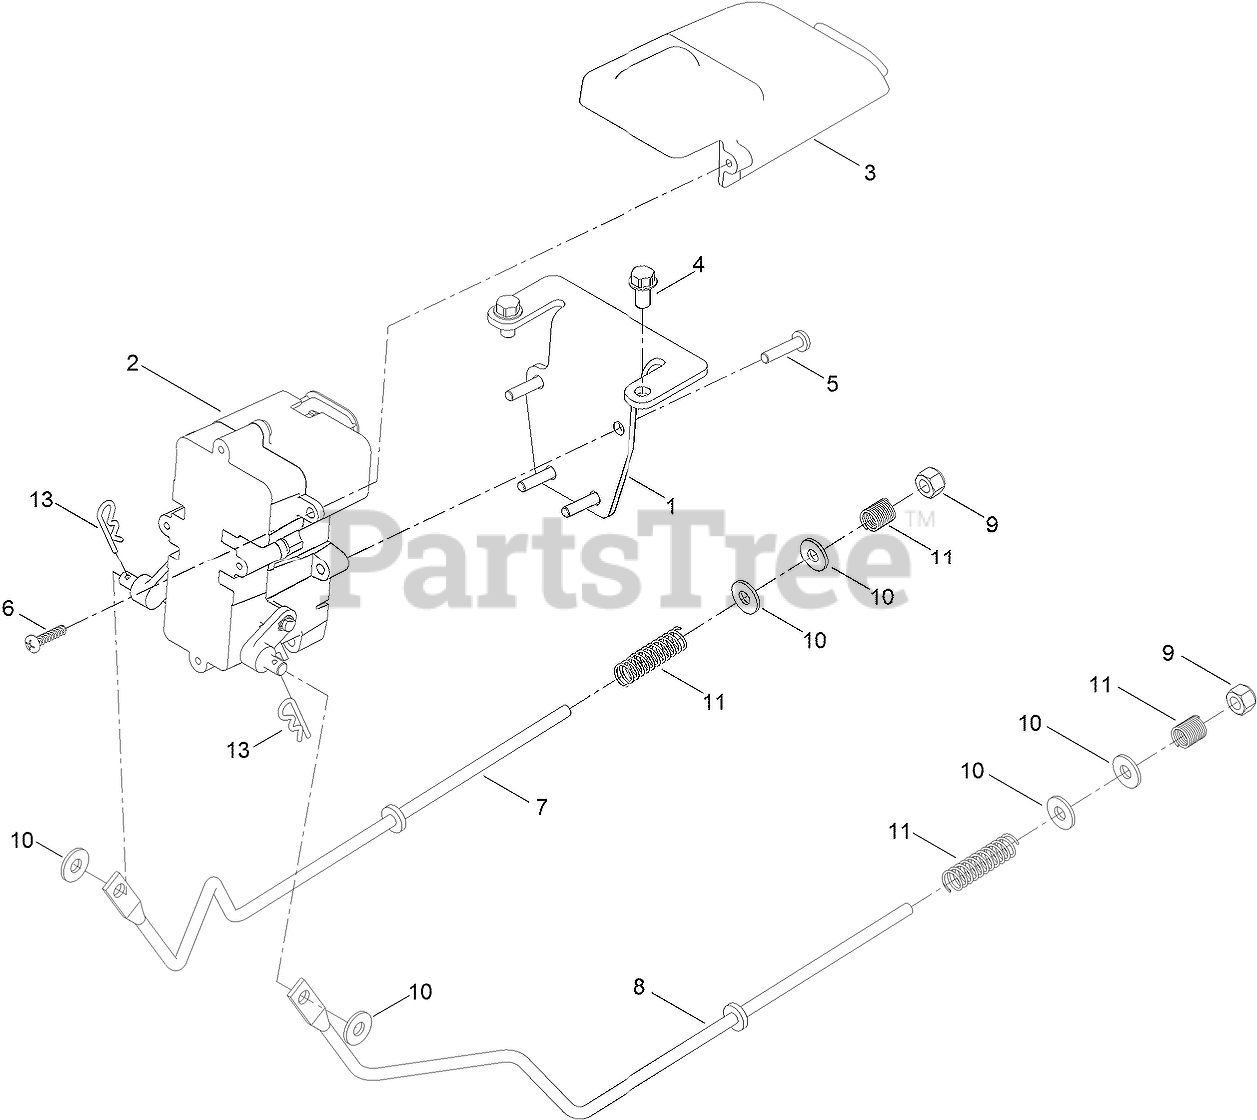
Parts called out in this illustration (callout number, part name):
1	BRACKET-MOUNT, BRAKE
2	BRAKE BOX ASM
3	COVER-CONNECTOR
4	SCREW-HWH
5	SCREW-PPH
6	SCREW-PPH
7	ROD-BRAKE, RH
8	ROD-BRAKE, LH
9	NUT-HEX
10	WASHER
11	SPRING-COMPRESSION
13	PIN-HAIR
